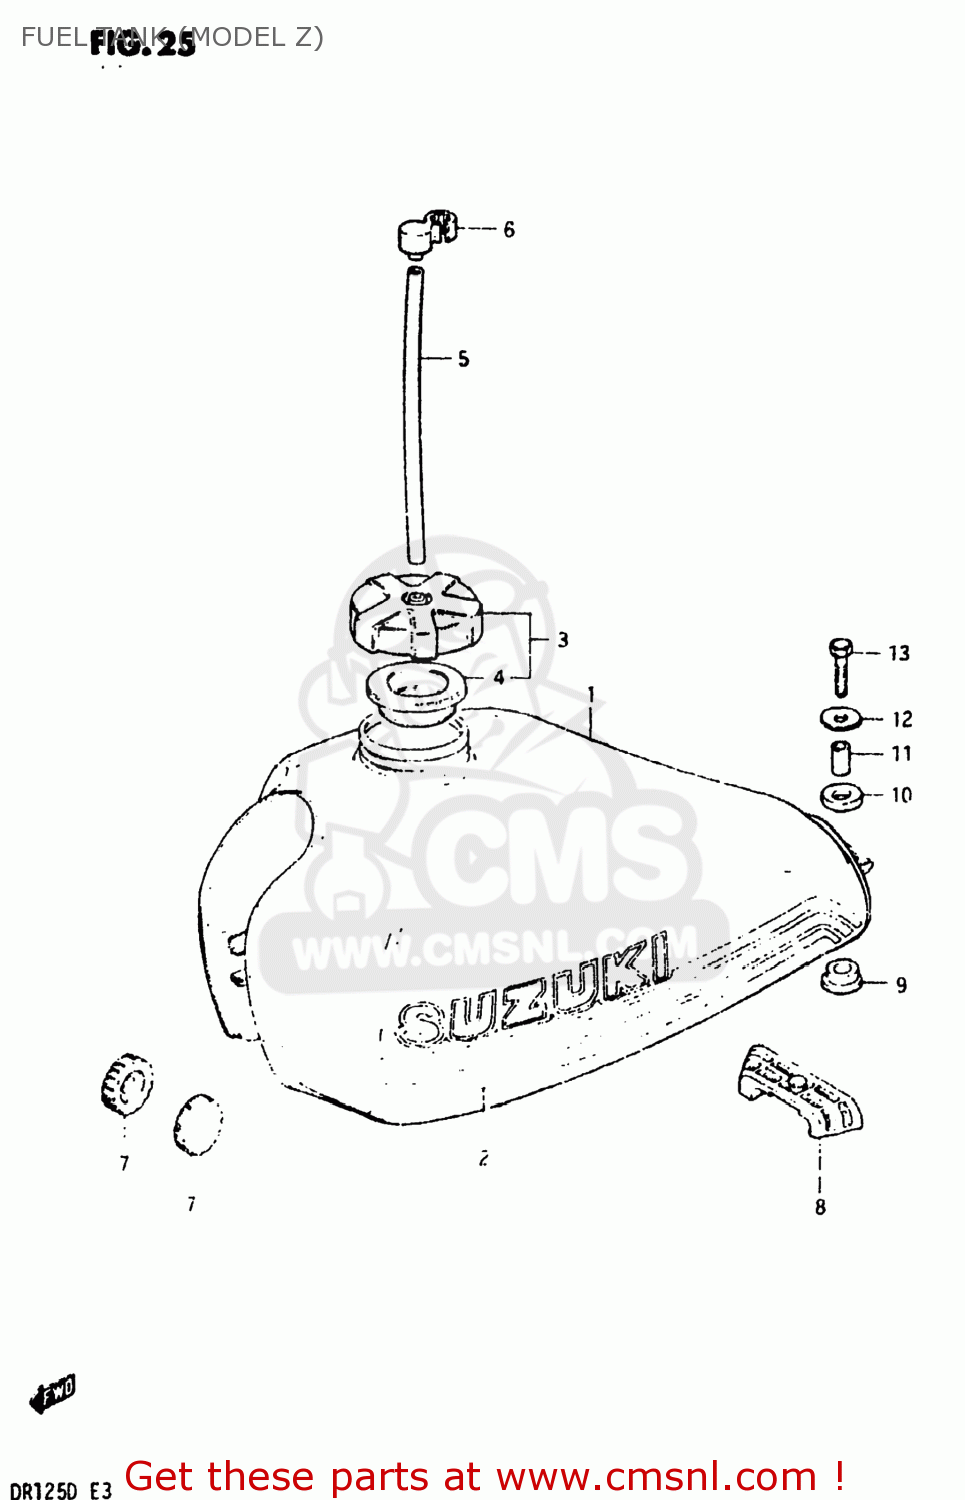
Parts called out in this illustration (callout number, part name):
1	TANK ASSEMBLY,FUEL
2	TAPE SET,FUEL TANK
3	CAP SET,FUEL TANK
4	GASKET (NAS)
5	HOSE
6	CLAMP,FUEL TANK BREATHER HOSE
7	CUSHION
8	CUSHION,FUEL TANK
9	CUSHION
10	CUSHION
11	SPACER(8.5X12X19)
12	WASHER (8.5X29X1.6)
13	BOLT (8X30)
